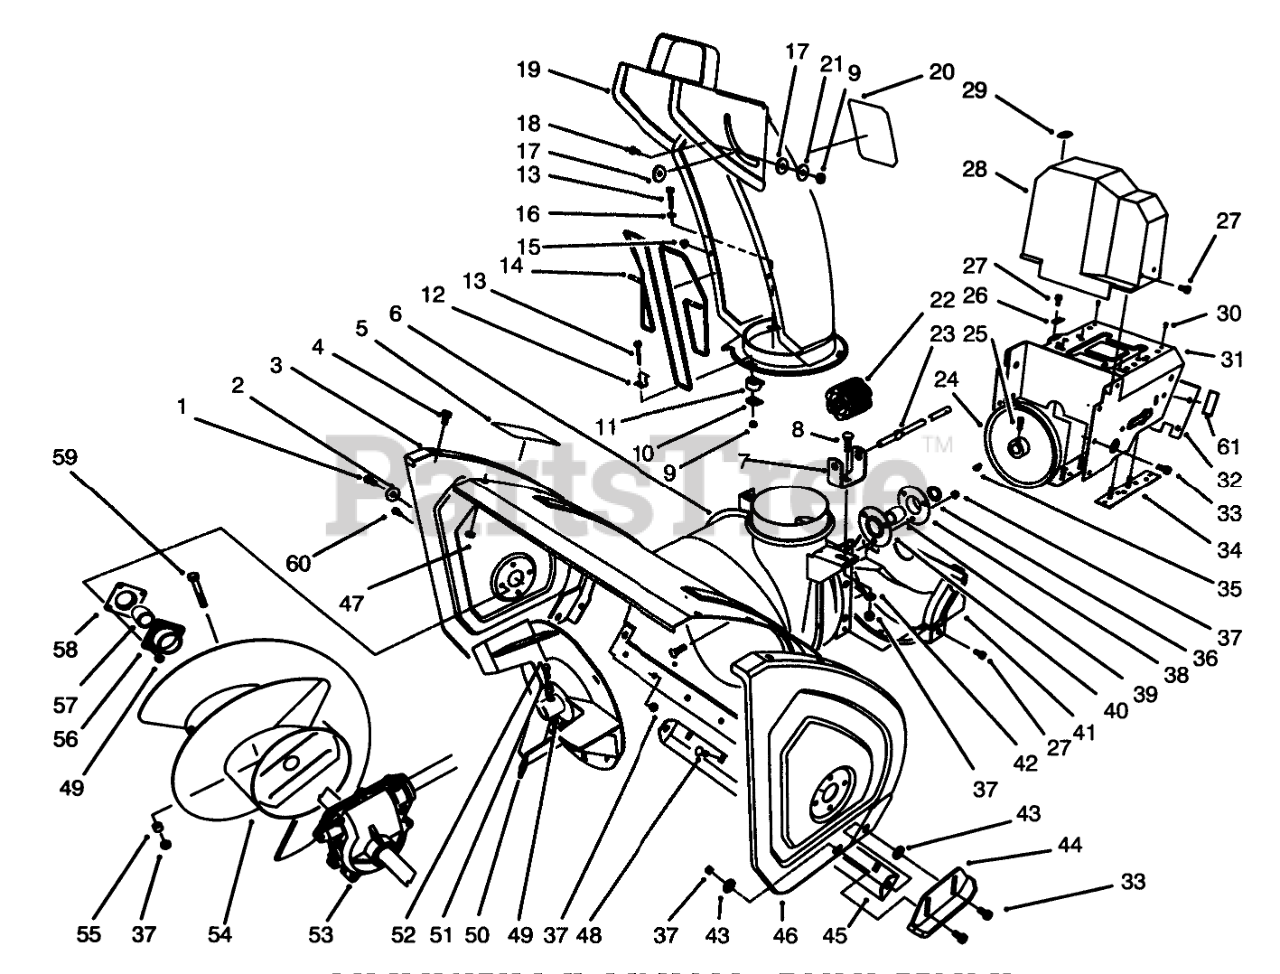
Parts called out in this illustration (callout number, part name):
1	SCREW-HH
2	WASHER
3	Plate-Side
4	SCREW-HHF
5	DECAL-WARNING, AUGER
6	Housing-28"
7	BRACKET-WORM, CHUTE
8	BOLT-CARR
9	NUT-LOCK, NI
10	PLATE-RETAINER, CHUTE
11	RETAINER-CHUTE
12	CLIP-GUARD, CHUTE
13	SCREW-HSH
14	GUARD-CHUTE
15	NUT-PUSH
16	WASHER-FLAT
17	WASHER-PLASTIC
19	Assembly
20	Decal-Danger
21	WASHER-FLAT
22	GEAR-WORM
23	ROD-CHUTE, LOWER
24	PULLEY-IMPELLER
25	SCREW-SET, SQH
26	RETAINER-CABLE
27	SCREW-HWH
28	COVER-BELT, UPPER
29	COVER-CABLE
30	RIVET-POP
31	Frame-Engine
32	Cover-Frame, Engine
33	SCREW-HHF
34	PLATE ASM FRM LH 11 B&S
35	KEY-WOODRUFF
36	WASHER-THRUST
37	NUT-LOCK, NI
38	Flange-Bearing (Rear)
39	BEARING-BALL
40	Flange-Bearing (Front)
41	COVER-BELT, LOWER
42	WASHER-PLAIN
43	WASHER
44	Skid
45	Blade-Scraper
46	Plate-Side
47	NUT-LOCK, NI
48	SCREW-CARR
49	NUT-LOCK, NI
50	Impeller
51	SPACER
52	SCREW-HHF
53	LH AUGER GEARCASE ASM
54	Auger-R.H.
55	SPACER-HUB, AUGER
56	BEARING-FLANGE, FRONT
57	BEARING
58	BEARING-FLANGE, REAR
59	SCREW-HH
60	SCREW-HH
61	DECAL
